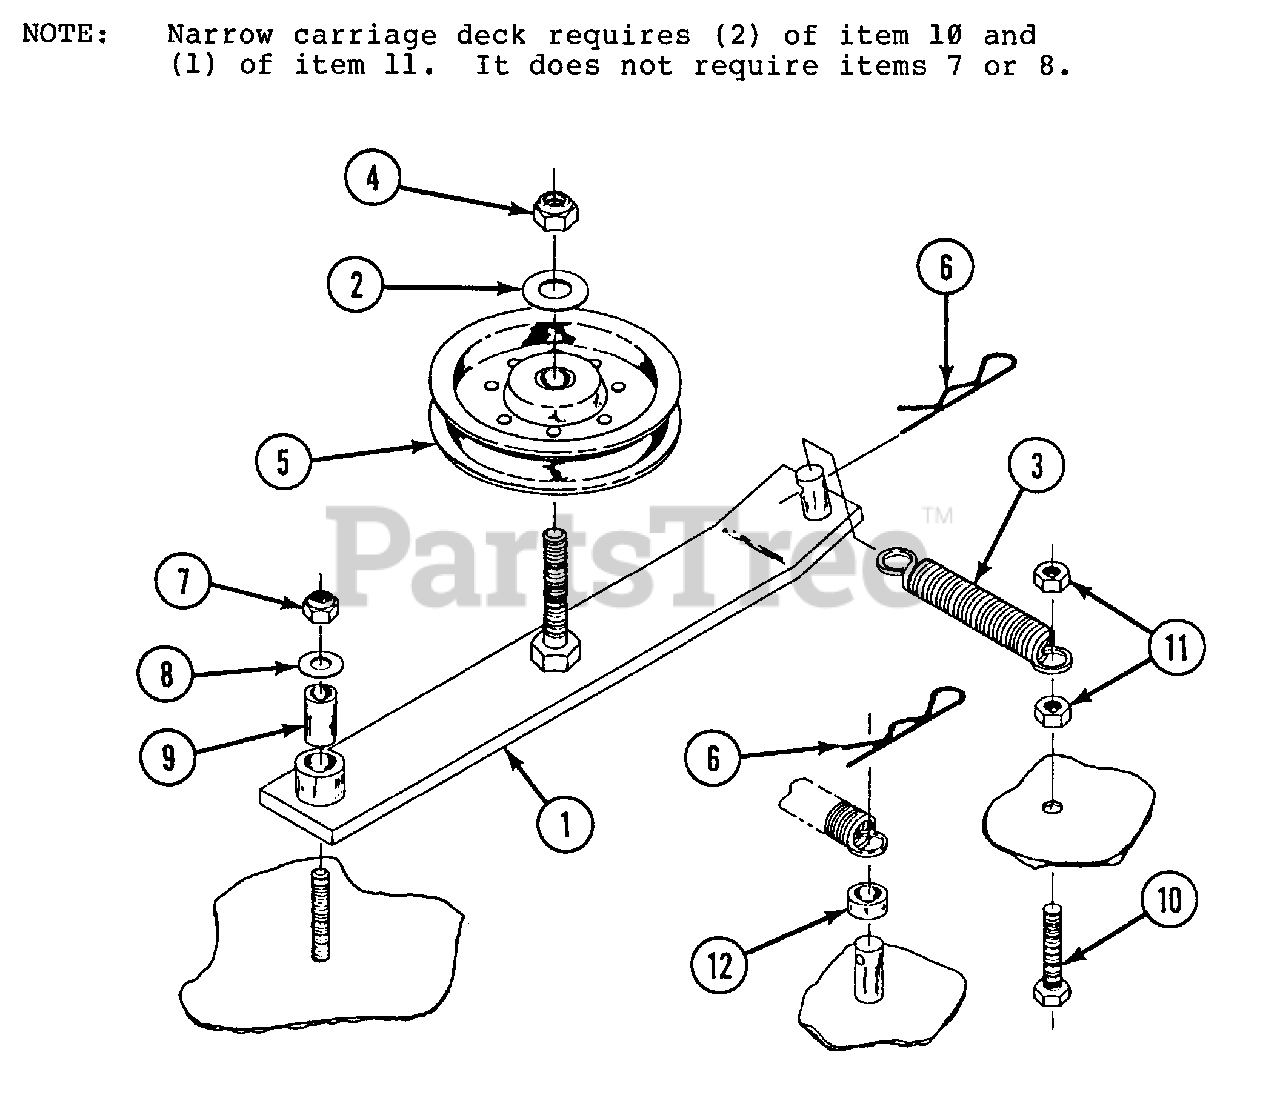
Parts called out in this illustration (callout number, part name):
1	SINGLE IDLER ARM WELDMENT
2	FLAT WASHER, 1/2"
3	SPRING, EXTENSION, 3/4 X 4" O.A.L.
4	LOCKNUT, 1/2-13 HEX. NYLOCK
5	PULLEY, FLAT IDLER, 1/2 BORE, 4" O.D.
6	PIN, HAIR SPRING, 1/8 X 2-1/2
7	LOCKNUT, 3/8-16 HEX. NYLOCK
8	WASHER, FLAT STD. 3/8 W SERIES
9	BEARING OILITE, 3/8 I.D. X 5/8 O.D.
10	CAPSCREW, HX HD:3/8-24NF X 1 1/4 GR. 5
11	LOCKNUT, 3/8-24, M-F
12	SPRING SPACER
